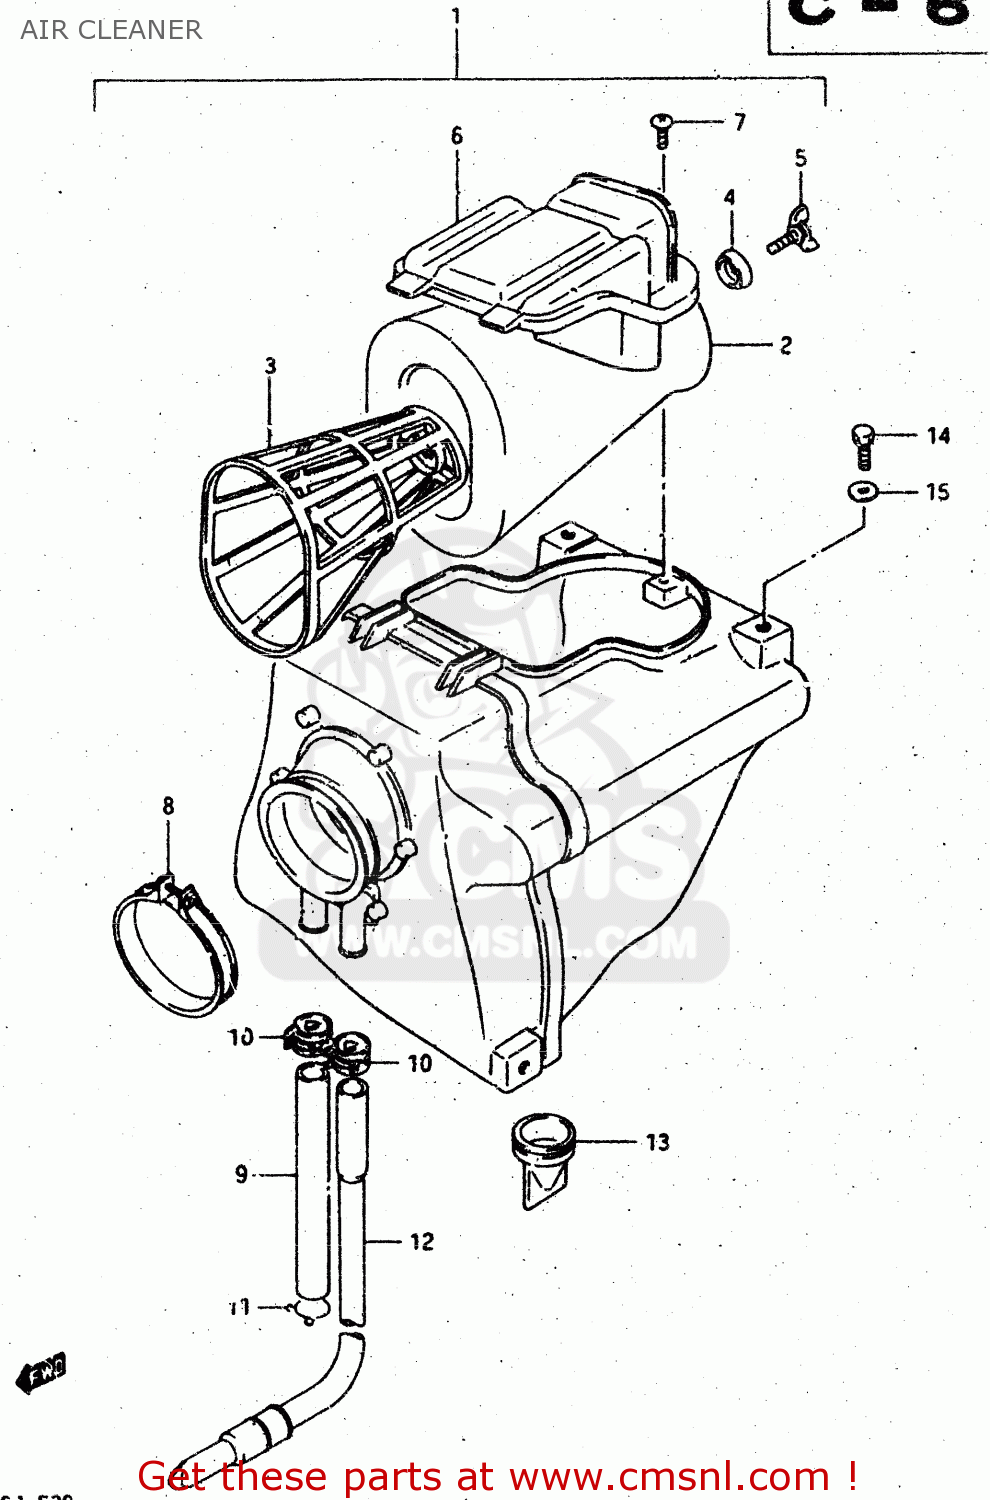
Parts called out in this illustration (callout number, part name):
1	CLEANER ASSEMBLY
2	FILTER,AIR CLEANER
3	HOLDER
4	WASHER,FILTER HOLDER
5	BOLT,AIR CLEANER
6	CAP,AIR CLEANER
7	SCREW
8	CLAMP
9	TUBE,BREATHER
10	CLIP
11	CLIP
12	DRAIN TUBE
13	HOSE,AIR CLEANER DRAIN
14	BOLT(6X14)
15	WASHER
